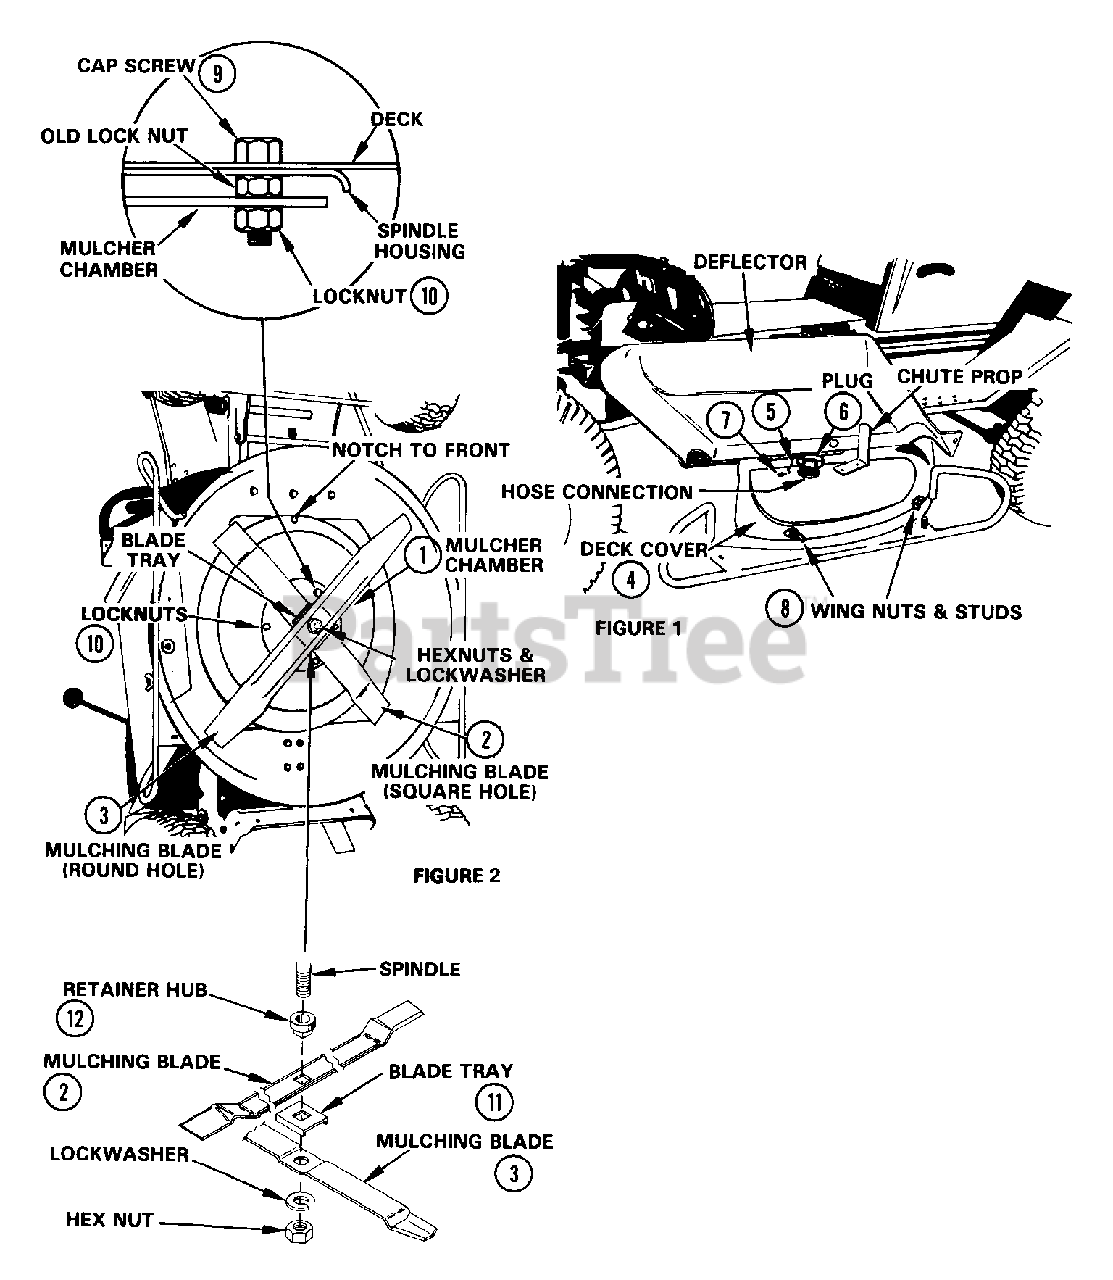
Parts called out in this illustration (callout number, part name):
1	MULCHER CHAMBER
2	MULCHING BLADE
3	MULCHING BLADE
4	MULCHER COVER WITH DECAL
7	RVT-POP.125 X .294 DOME
8	NUT-WING .312-18 YWZC
9	BLT-HEX .38-16X1.25 PL GR 2
10	NUT-LK-CTR .375-16 GR A PL
11	BLADE TRAY
12	RETAINER HUB
